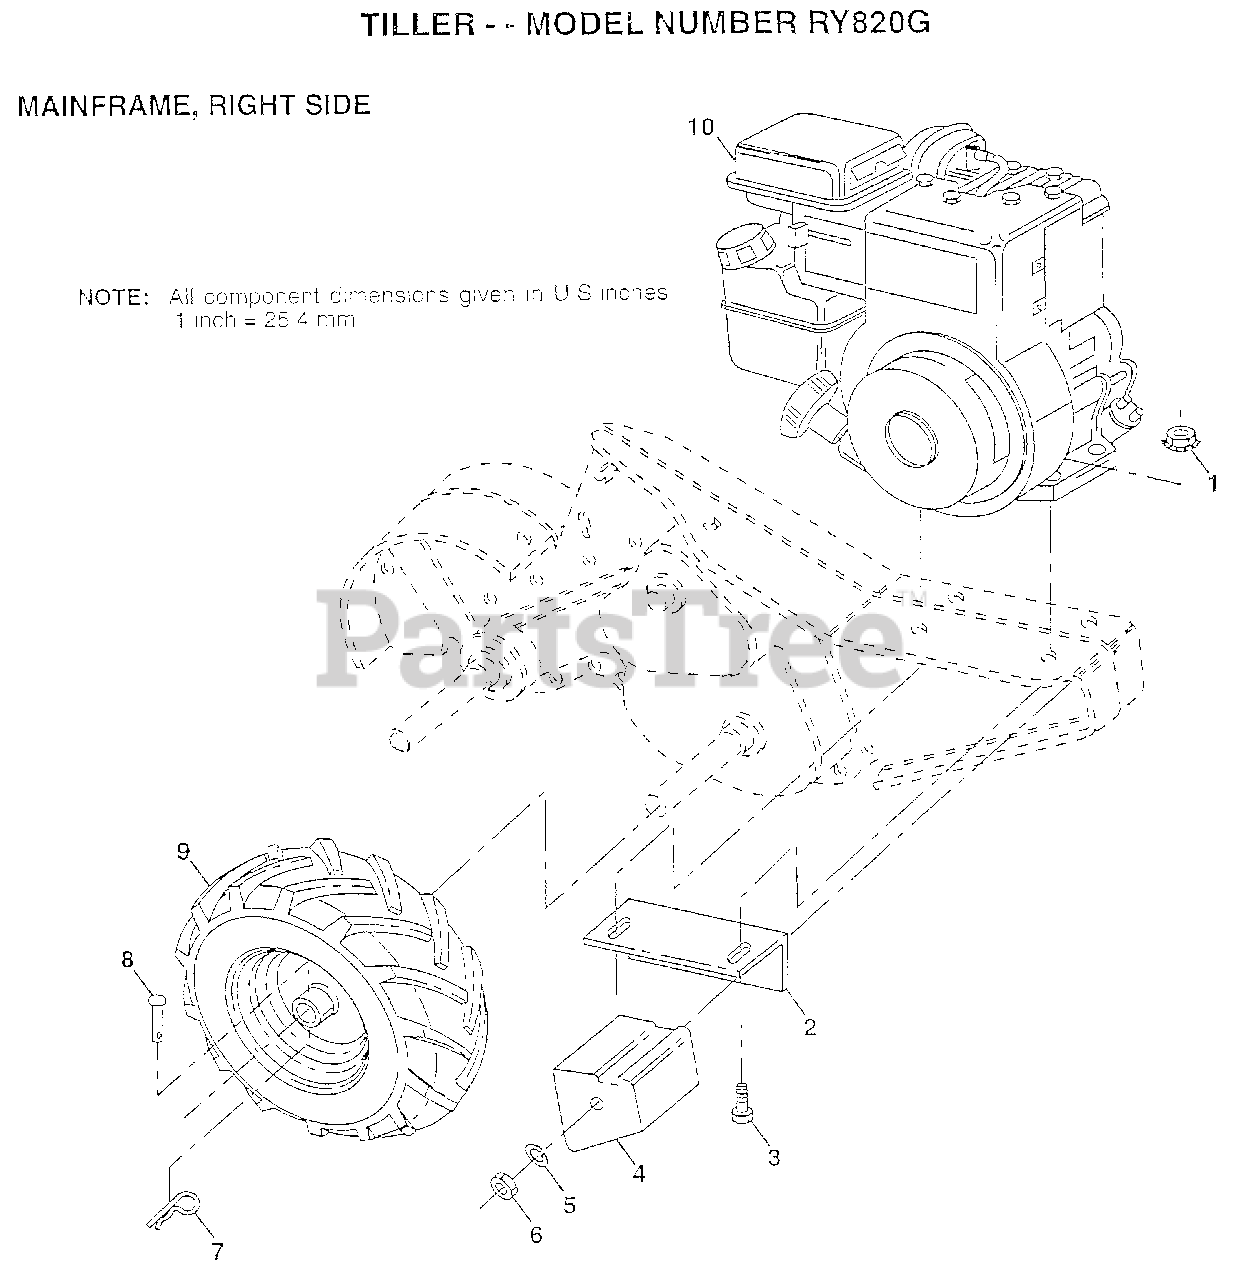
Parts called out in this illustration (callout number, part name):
2	BRACKET RH CRT
3	BOLT.HEX.5/16-1.5
4	COUNTERWEIGHT CRT
5	LOCKWASHER
6	NUT.HEX.3/8-16UNC
7	RETAINER M
8	RIVET.DRILL.1.75
9	TIRE.CHV.13X5.0-6
